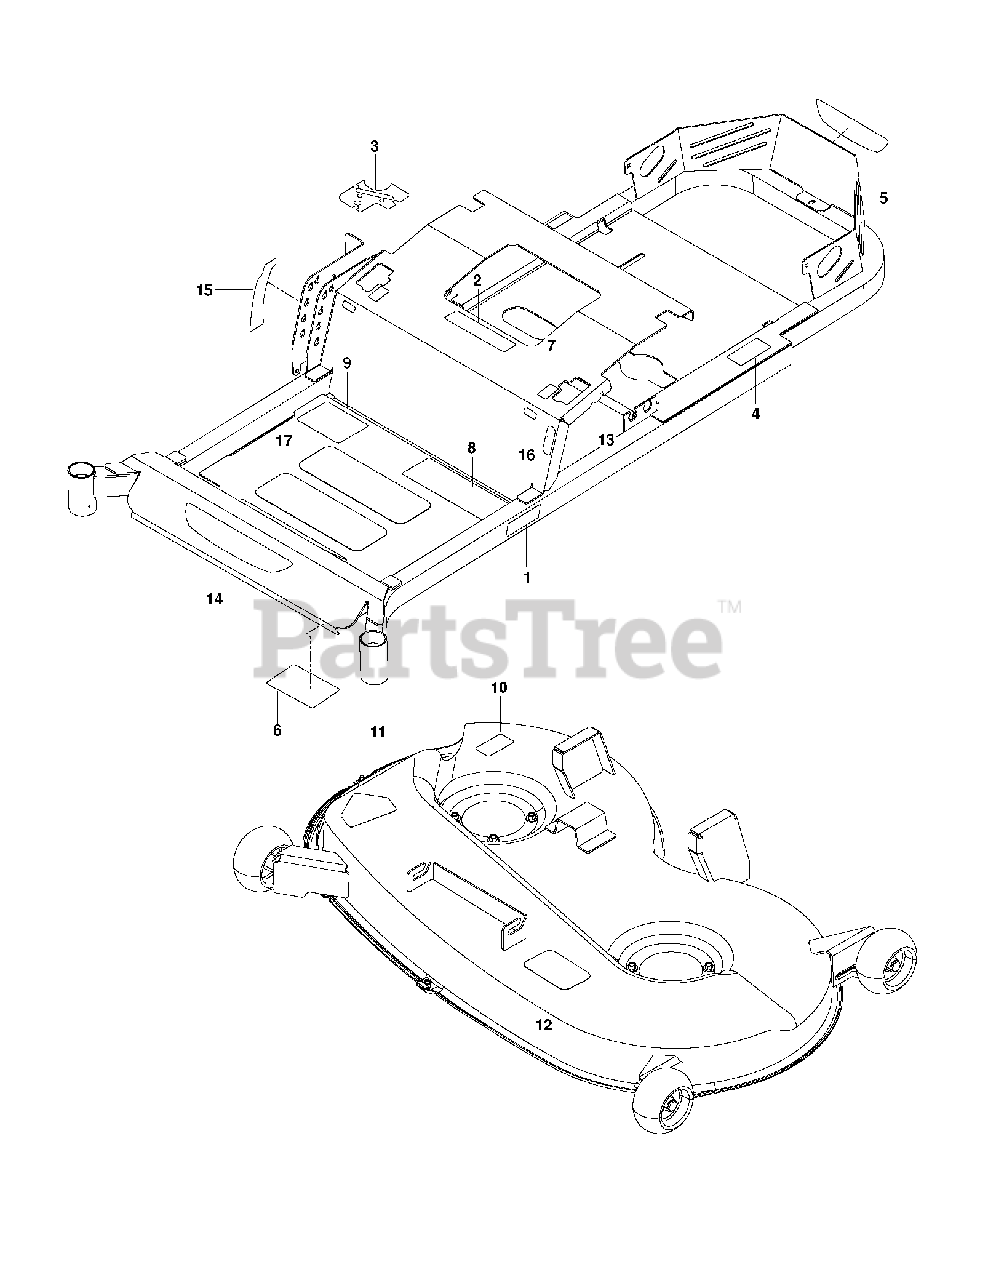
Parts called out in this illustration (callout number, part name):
2	DECAL, BATTERY
4	DECAL, DO NOT MOUNT
6	DECAL, SERVICE
8	DECAL, SAFETY WARNING
9	DECAL ZTR STARTING DECAL
10	Deflector Shield Warning Decal
11	DECAL, DECK DEFLECTOR, WARNING
12	DECAL, BELT ROUTING
17	ANTI-SKID PAD
